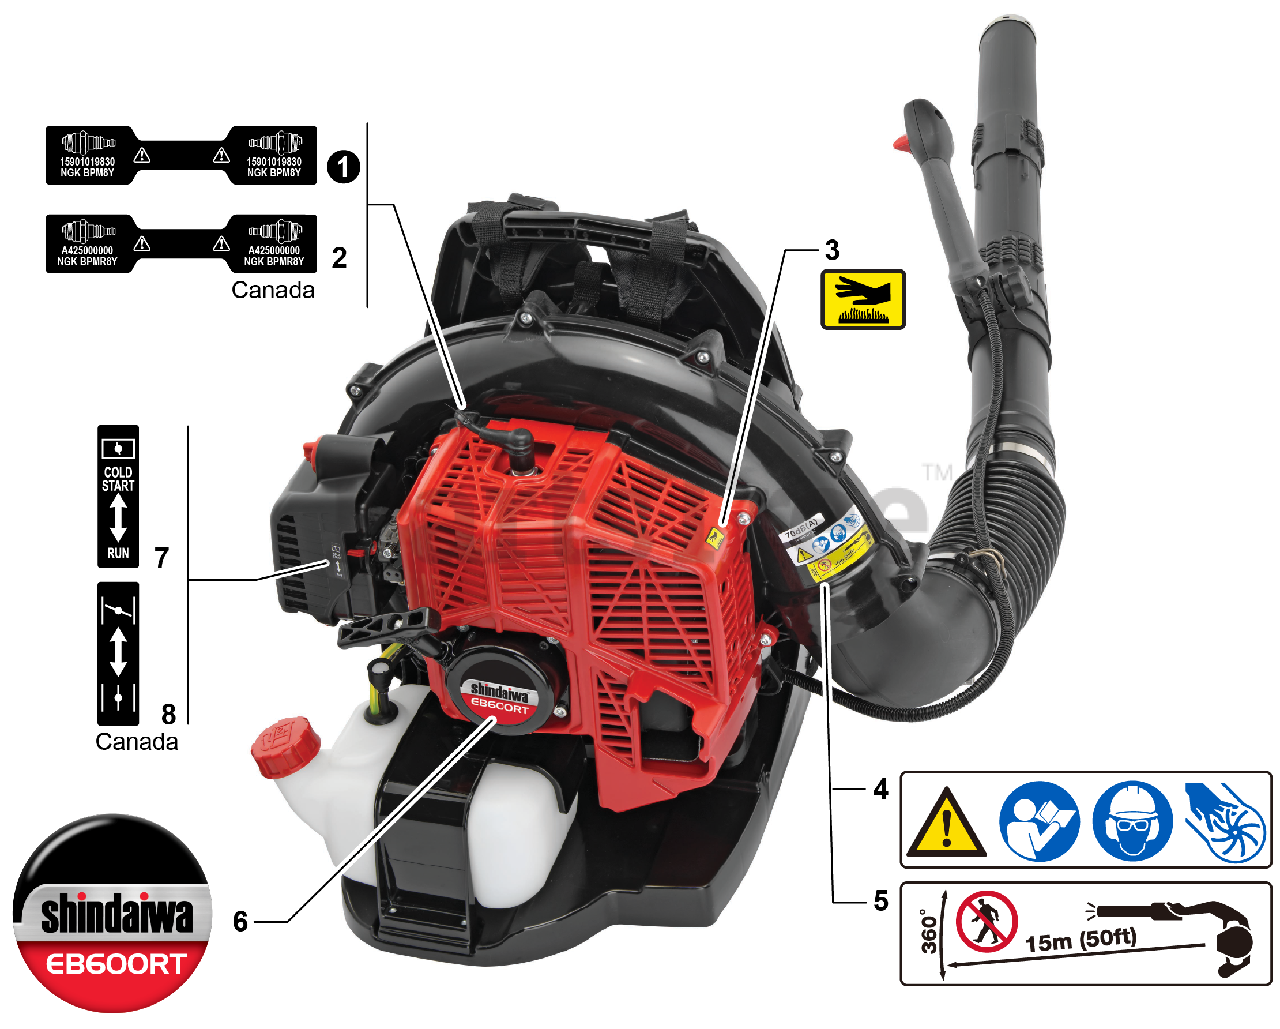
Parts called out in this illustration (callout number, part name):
1	LABEL, SPARK PLUG - BPM8Y
2	LABEL, SPARK PLUG - BPMR8Y
3	LABEL, CAUTION - HOT
4	LABEL, CAUTION - ISO
5	LABEL, CAUTION - BLOWER
6	LABEL - MODEL EB600RT
7	LABEL, CHOKE
8	LABEL, CHOKE
